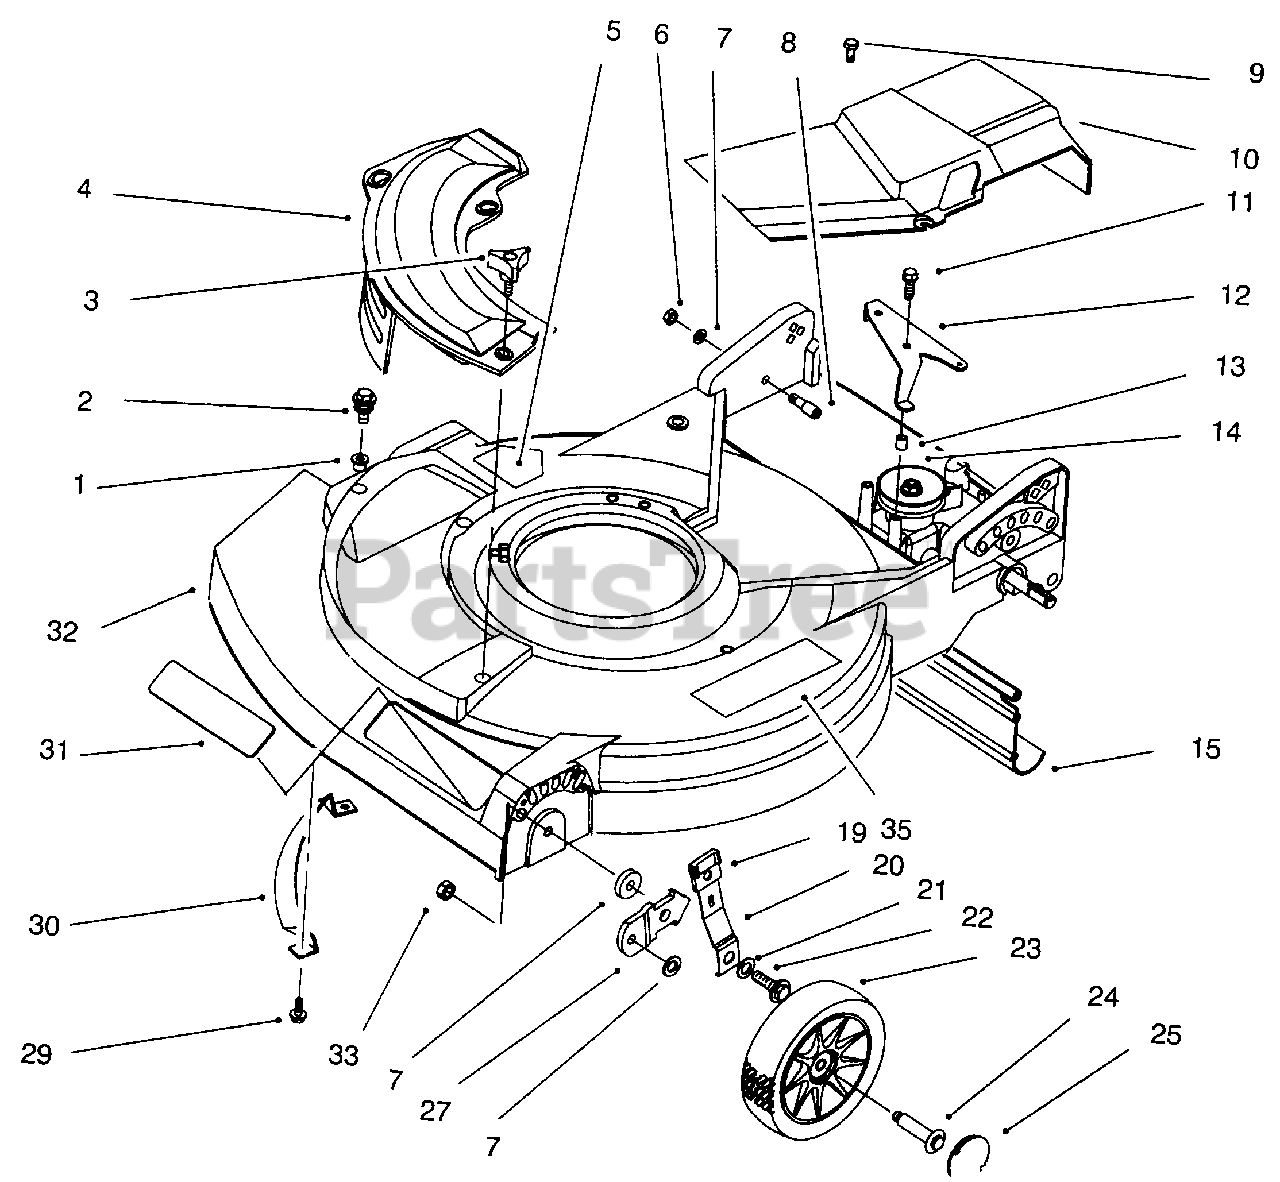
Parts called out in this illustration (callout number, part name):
2	Screw-Thread Forming
3	Knob
4	Cover-Plate, Mulch
5	Decal-Danger (English)
7	Washer-Wheel Bolt
8	Bolt-Shoulder
10	Cover-Drive
11	Screw
12	Bracket-Actuator
14	Gear Case Assembly
15	Shield-Trailing
19	Knob-Spring Arm
20	Spring Arm Assembly
21	Washer-Belleville
22	Bolt-Shoulder
23	Wheel-6"
24	Bolt-Wheel
27	Bracket-H. O. C.
30	Bar-Toe
31	Decal-Deck
32	Housing-21 (Incl. Ref. #5 & 35)
35	Decal-Warning
